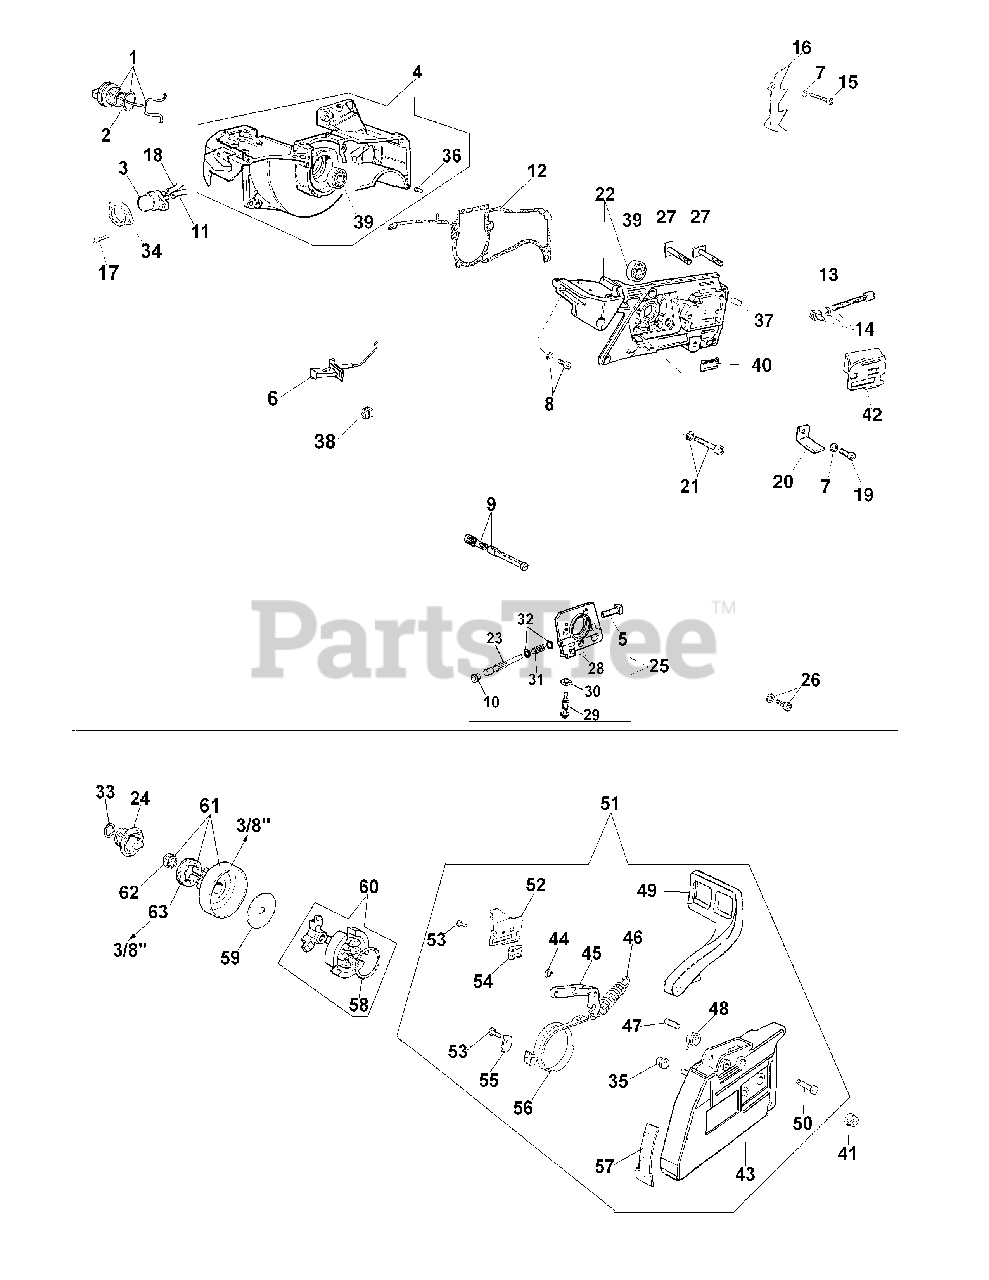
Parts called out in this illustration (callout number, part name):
1	CAP
6	STARTER LEVER
12	GASKET
13	SCREEN-LOCK
14	CHAIN ADJUST
20	CHAIN CATCHER
24	WORM GEAR
25	OIL PUMP ASSY
29	ADJUST.SCREW.
34	PRIMMER GUARD
37	BREATHERTANK
43	CHAIN COVER
51	CHAIN COVER
54	CHAIN CATCHER
60	COMPL.CLUTCH
61	CLUTCH DRUMP.3/8''
63	RIM SPROCKET P .3/8''
